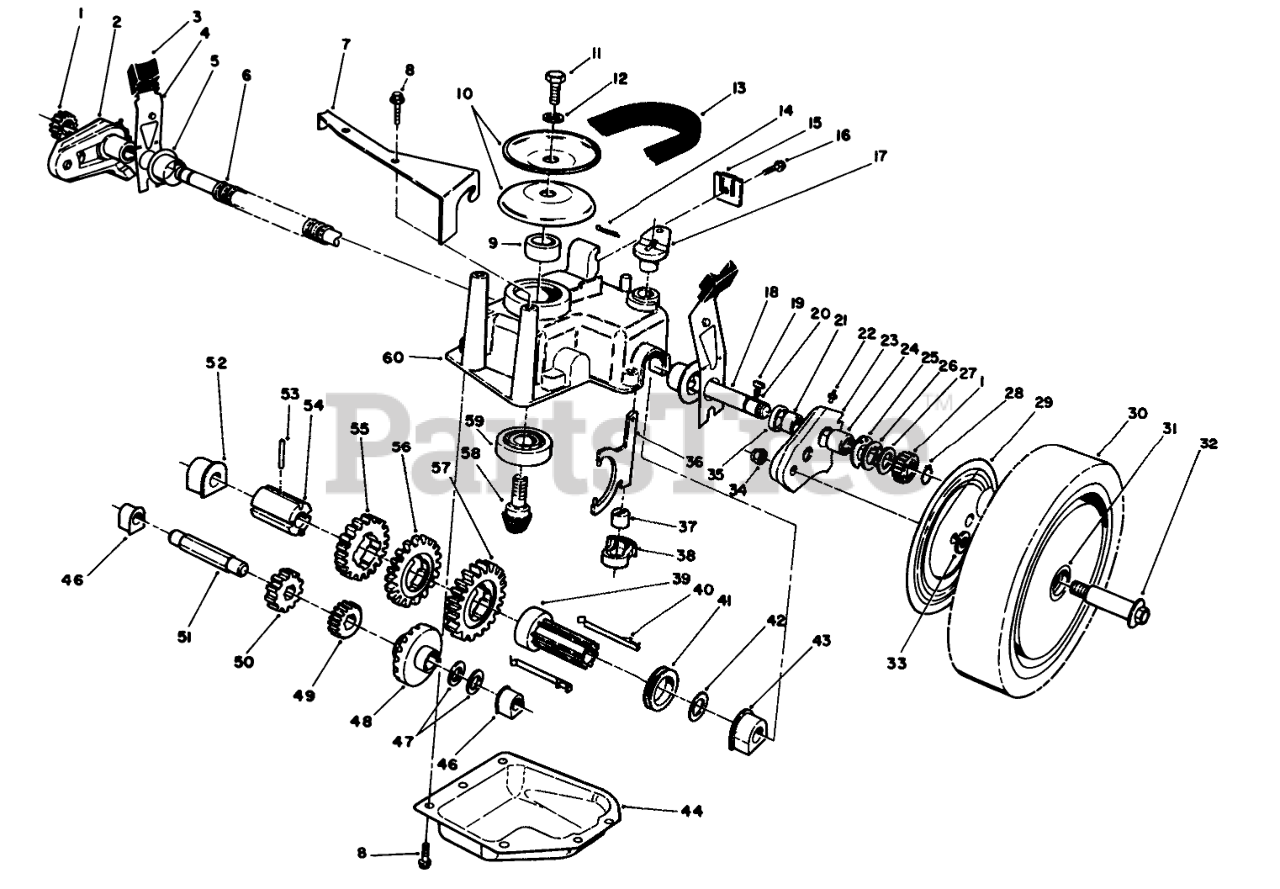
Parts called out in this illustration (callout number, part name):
1	GEAR-PINION
2	Pivot Arm Assembly-R.H. (Incl. Ref. #21, 22, 24 & 35)
3	KNOB-ARM
4	SPRING ARM ASM SP
5	CAP-END
6	CONDUIT-CONVOLUTED, SPLIT
7	Bracket-Guide
8	SCREW-HWHTF
9	SPACER
10	Pulley Half
11	NUT-HEX
12	WASHER-FLAT
13	V-BELT E
14	PIN-COTTER
15	Cable Clamp
16	SCREW-HWHTF
17	SHIFT LEVER
18	ASM - OUTPUT SHAFT
19	KEY RECTANGULAR
20	SPRING-COMPRESSION
21	BUSHING
22	FITTING-GREASE
23	Pivot Arm Assembly-L.H. (Incl. Ref. #21, 22, 24 & 35)
24	BEARING-ROLLER
25	INNER THRUST WASHER
26	WASHER-THRUST, OUTER
27	WASHER-THRUST, OUTER
28	PIN-ROLL
29	WHEEL COVER
30	Wheel-Tire & Gear Assy. (Incl. Ref. #31)
31	BUSHING
32	WHEEL BOLT
33	WASHER
34	Nut
35	SEAL-OIL
36	YOKE-SHIFT
37	BUSHING-YOKE
38	RETAINER-FORK, SHIFT
39	Sleeve-Shift Key
40	Key Shift
41	SHIFT COLLAR
42	WASHER-PLAIN
43	BUSHING-OUTPUT
44	Cover-Gearcase
46	BUSHING
47	WASHER-THRUST
48	Gear-Bevel
49	PINION-20T
50	PINION-25T
51	SHAFT-INTERMEDIATE
52	BUSHING
53	PIN-SPRING
54	SLEEVE-GEAR
55	GEAR-39T
56	GEAR-44T
57	GEAR-49T
58	Gear-Pinion
59	BEARING-BALL
60	CASE-GEAR, UPPER
